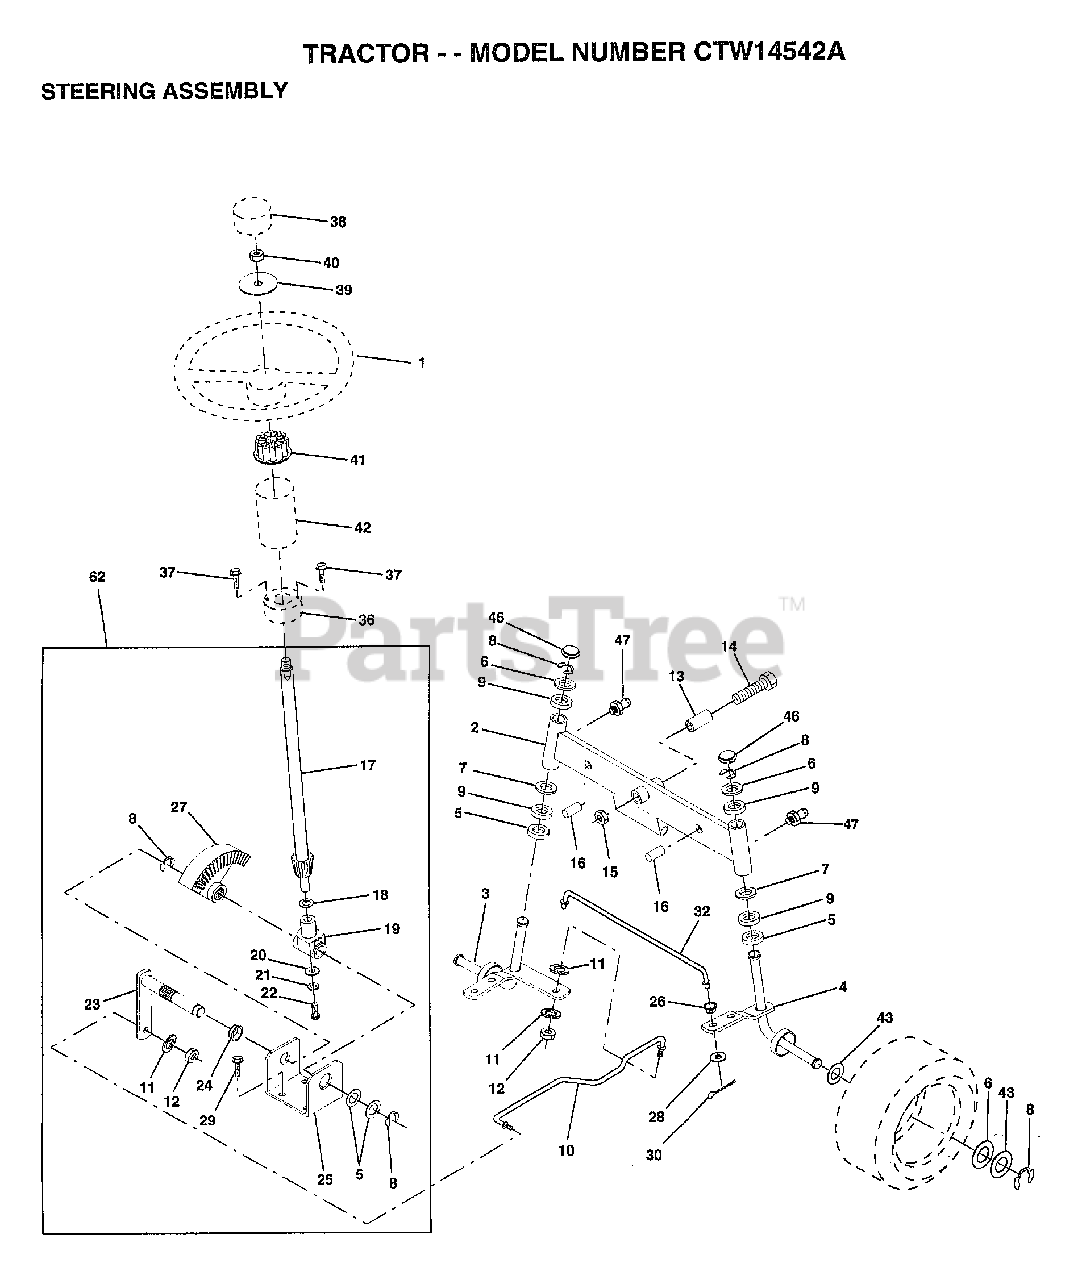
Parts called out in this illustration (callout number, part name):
1	WHEEL STR AYP BLK
2	AXLE ASM FRONT
3	SPINDLE LH
4	SPINDLE RH
5	WASHER .T
6	WASHER
7	WASHER
8	RING
9	COL. SRTG. BEAR.
11	LOCKWASHER
13	BEARING
14	BOLT HEX 5/8-11
15	"NUT-LOC,FLANGE LT"
16	AXLE PIN
17	SHAFT ASM
18	THRUST WASHER
19	SUPPORT.SHAFT
21	LOCKWASHER
22	"SCREW,SPECIAL"
24	NYLINER T
25	"BRKT,STEERING"
26	BUSHING.DRAGLINK
27	GEAR SECTOR
28	WASHER
29	SCREW
30	COTTER PIN
32	TIE ROD
38	CAP STEER AYP
39	WASHER T
40	GRIPCO NUT
41	ADAPTER-WHEEL LT
42	"TUBE, STR SHAFT"
43	WASHER
46	CAP
47	ZERK M
